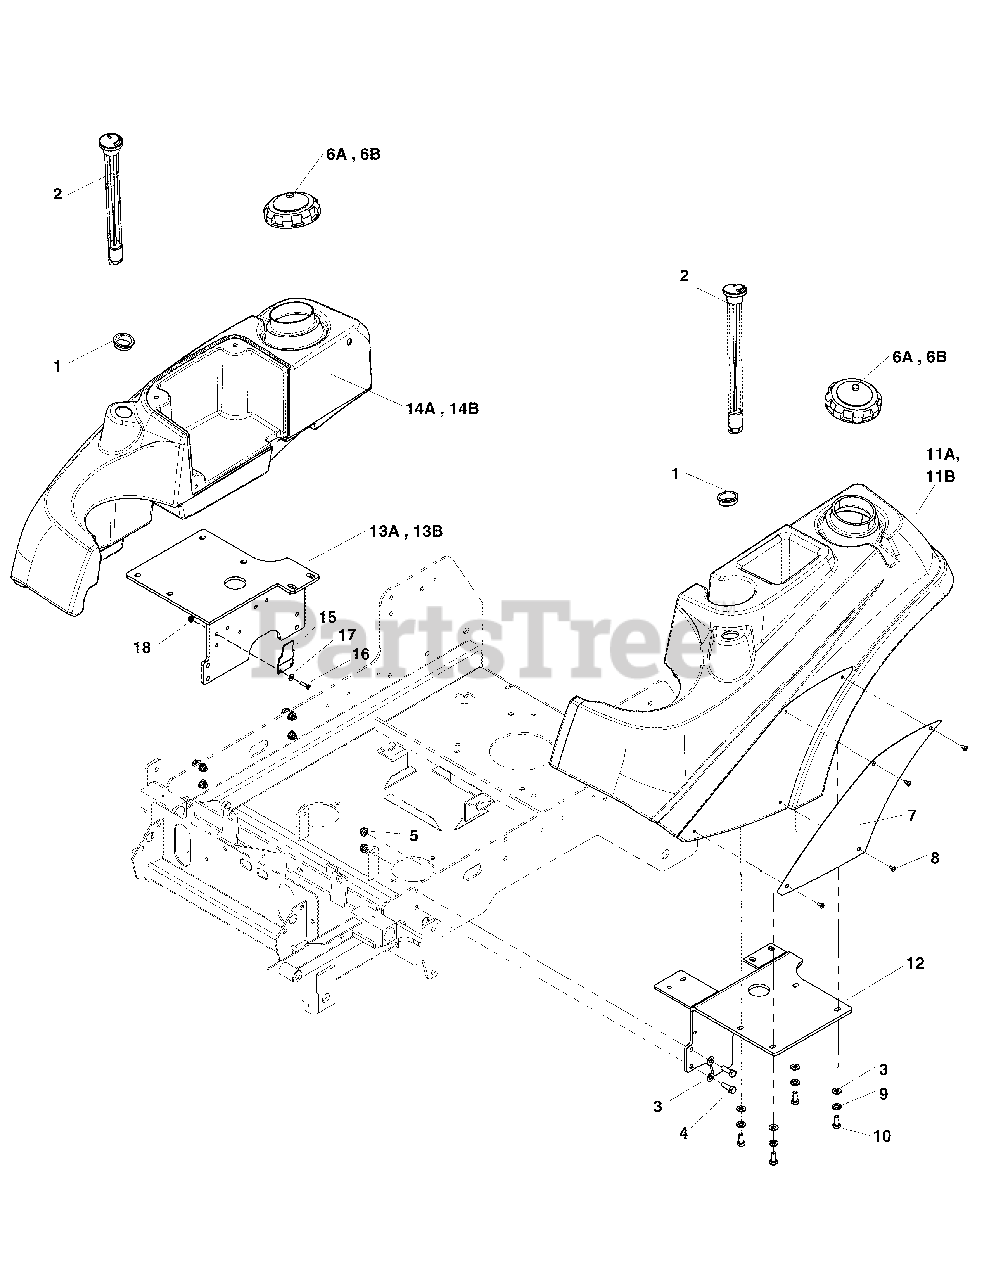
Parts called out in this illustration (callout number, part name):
1	GROMMET, FUEL GAGE
2	GAUGE, FUEL 12"
3	WASHER, 5/16" SAE
4	BOLT, 5/16-18 X 1" GD5
5	NUT, 5/16-18 HEX NYLOCK FLANGE
7	PLATE, TANK BADGE, COBALT - ORANGE
8	SCREW, Allen Head, #10-24 x 3/8"
9	WASHER, 5/16" LOCK
10	BOLT, 5/16-18 X 3/4 GD5
12	WELD, TANK MOUNT, LH - BLK
15	PLATE, FUSE BLOCK TAB
16	SCREW, #10-24 X 3/4 ROUND
17	WASHER, #10 SAE
18	NUT, #10-24 HEX
